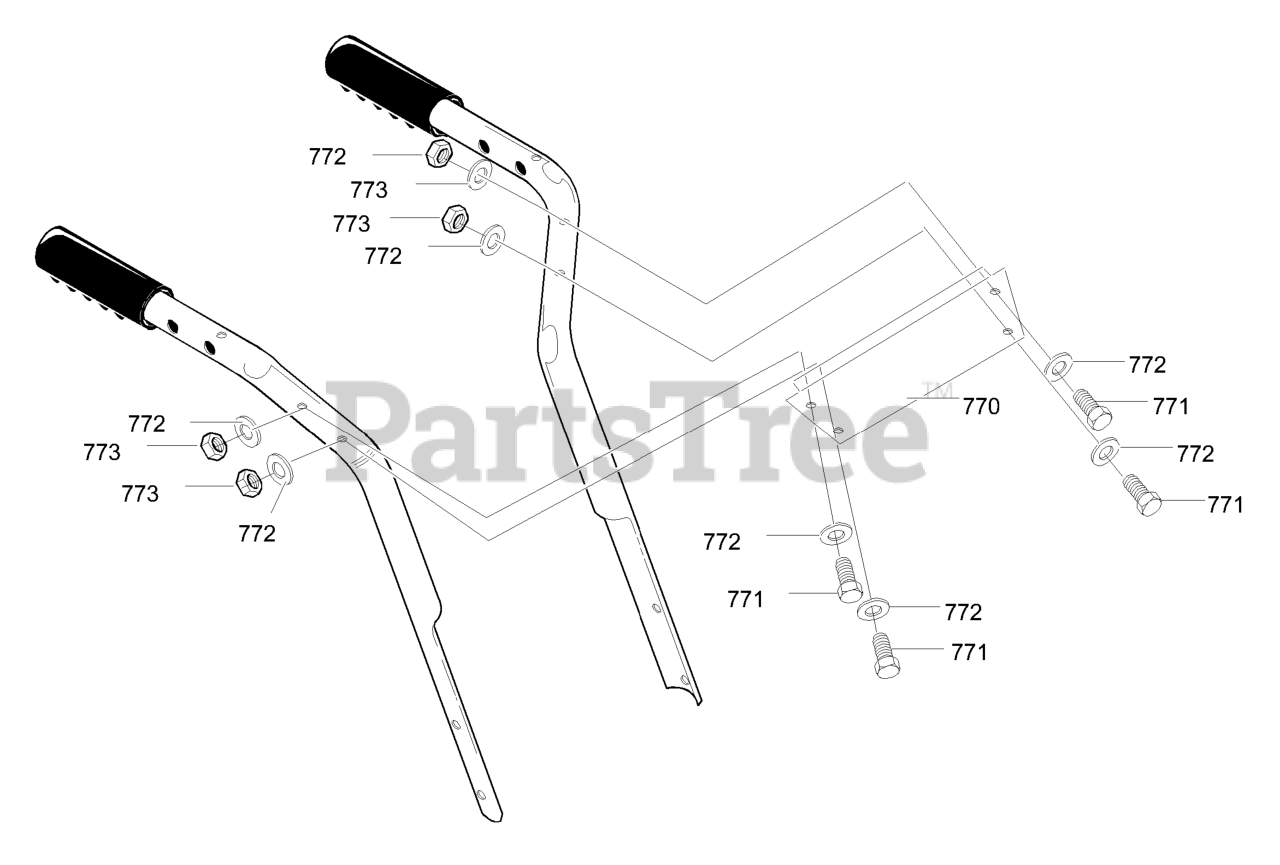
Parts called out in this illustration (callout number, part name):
770	PANEL, DECO
771	SCREW
772	FLATWASHER
